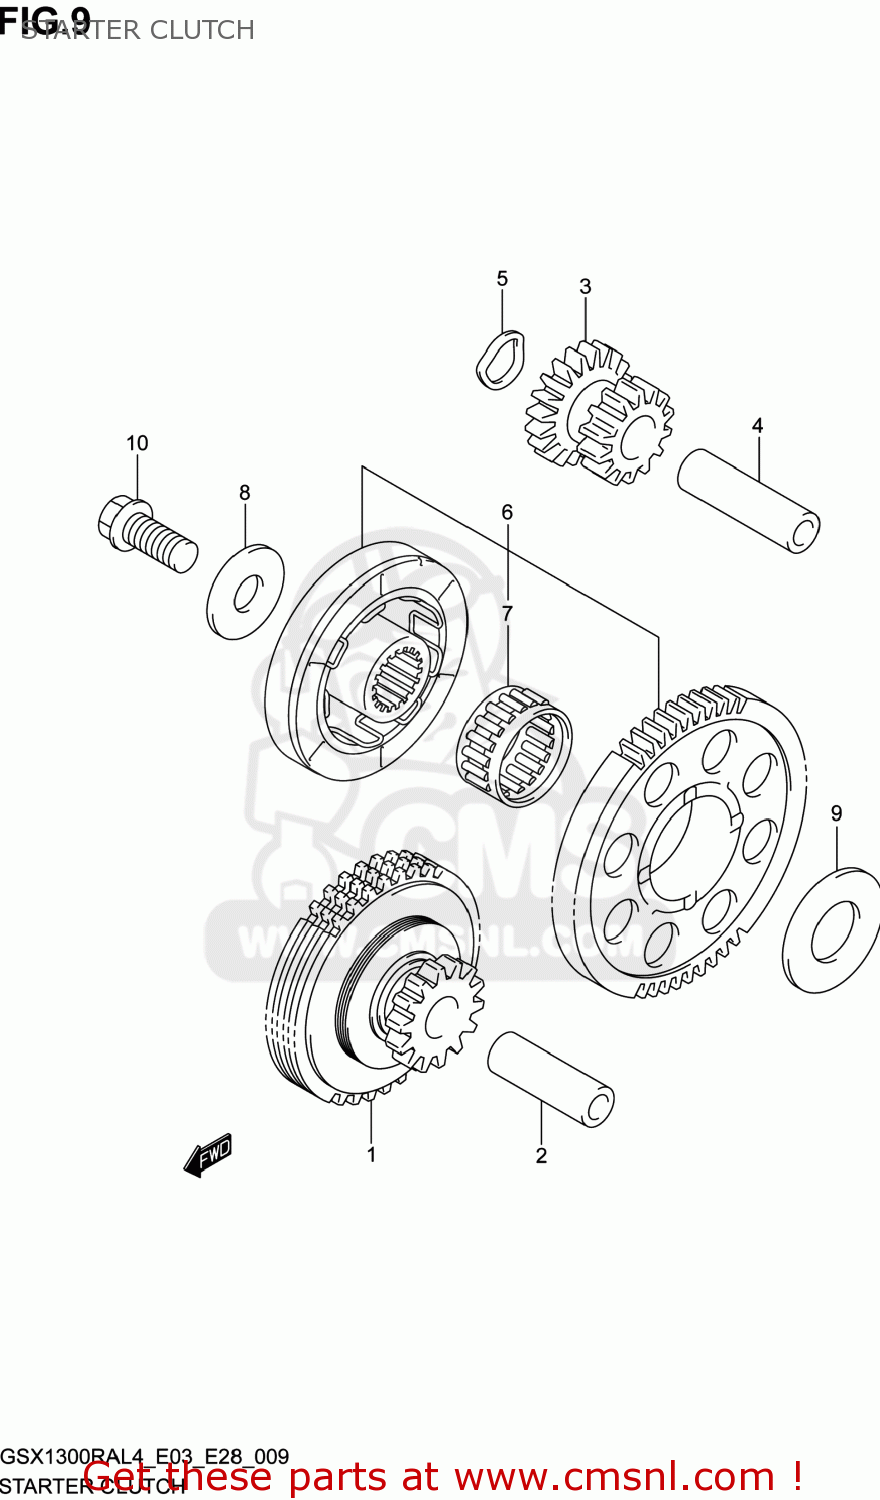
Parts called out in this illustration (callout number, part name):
1	LIMITER ASSY,START ID GR NO.1
2	PIN,STARTER IDLE GEAR NO.1
3	GEAR,STARTER IDLE NO.2
4	PIN ,PISTON
5	WASHER
6	CLUTCH SET,STARTER
7	BEARING(28X34X16.8)
8	WASHER
9	WASHER
10	BOLT(10X23)
